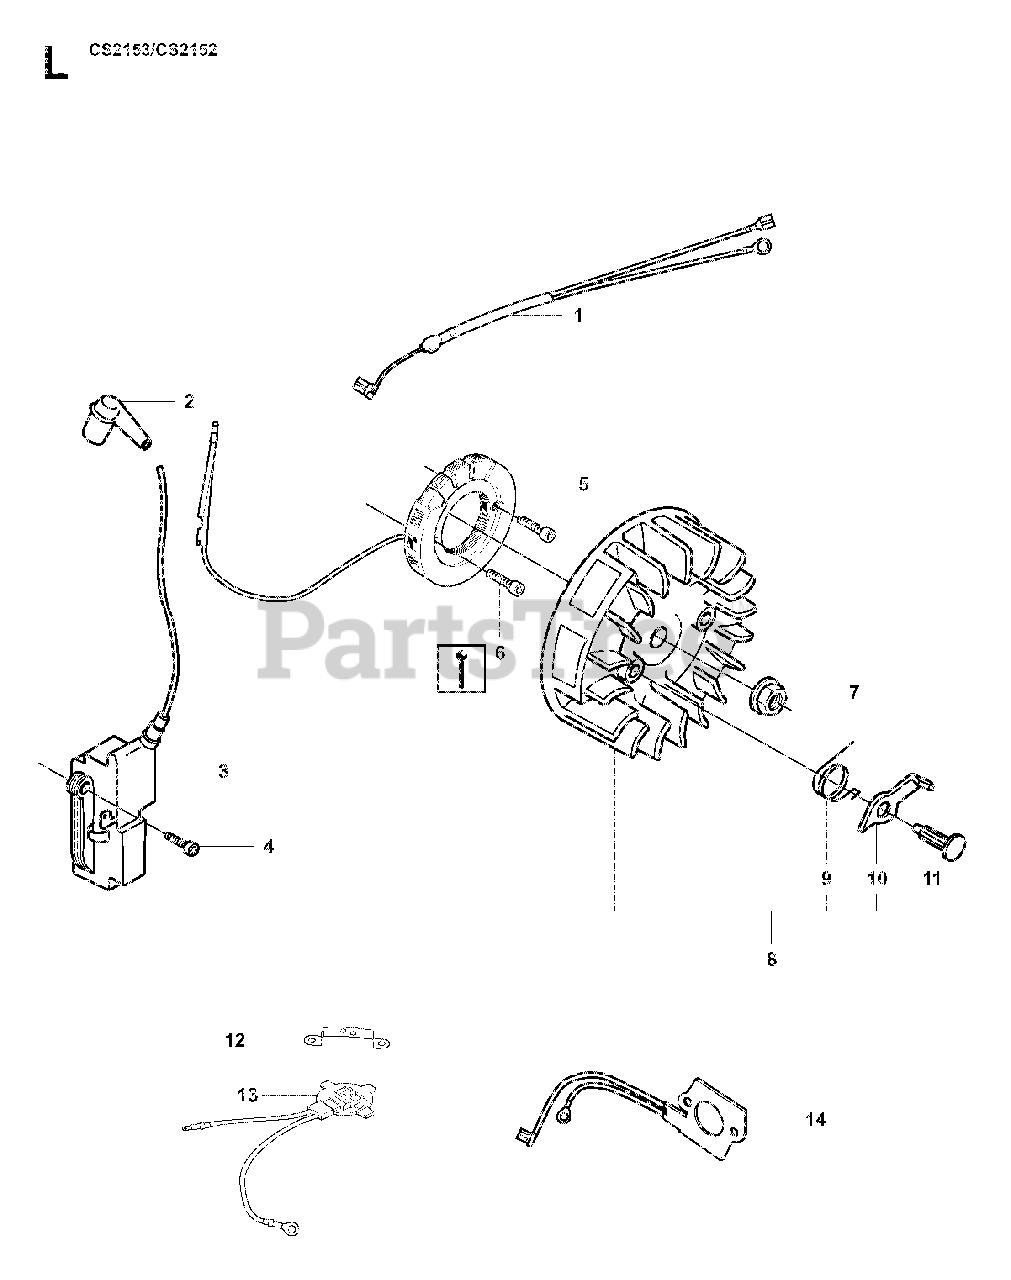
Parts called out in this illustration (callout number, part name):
1	CABLE ASSY
2	SPARK PLUG CONN. KIT
3	IGNITION MODULE
5	GENERATOR
7	NUT W/ WASHER
8	FLYWHEEL (G)
8	FLYWHEEL
9	%SPRING, STARTER CATCH
13	THERMOSTAT
